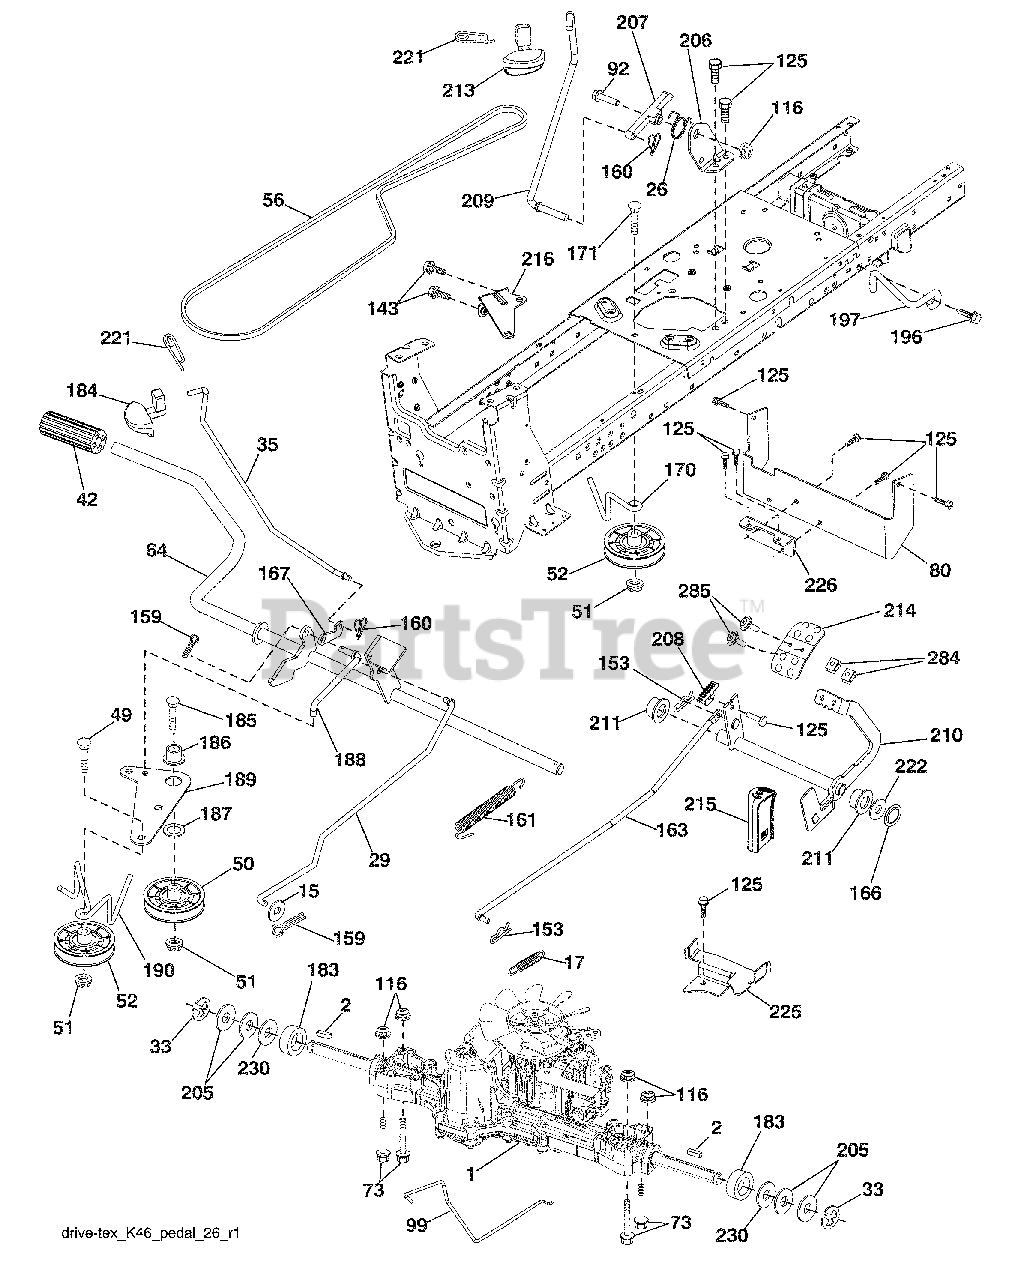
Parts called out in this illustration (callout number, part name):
1	Transaxle, TUFFTORQ K46 BT
15	Washer 13/32 x 13/16 x 16 Ga.
17	Spring, Brake
26	Spring Return Cruise
29	Rod, Brake
35	Rod, Brake, Park
42	Cover, Foot Pedal
50	Pulley Idler Flat
51	Lock Nut 3/8-16
52	Idler V-Groove 910" Offset
56	V-Belt, Drive
64	Shaft Asm. Pedal Brake Control
73	Bolt Hex Flghd 5/16-18 Gr. 5
80	Bracket Strap Torque
92	Bolt Fin Hex 5/16-18 unc x 1.25
99	Rod Spring Bypass
116	Nut Lock Hex Flange 5/16-18
125	Screw 5/16-18 x 3/4
143	Screw 5/16-18 x 1/2
153	Retainer Spring
159	Pin Cotter 1/8 x 3/4
160	Retainer Clip
161	Spring, Return, Clutch
163	Rod Pedal Control
166	Nut Push
167	Latch Brake Parking
170	Keeper Belt Centerspan
171	Bolt RDHD SQNK 3/8-16 unc x 2
183	Spacer Split
184	Handle Parking Brake
185	Bolt Rdhd Sqnk 3/8-16 x 2-3/4 Gr. 5
186	Spacer Retainer
187	Washer
188	Link Clutch Ground Drive
189	Bellcrank Ground Drive
190	Keeper Bellcrank Ground Drive
196	Screw 3/8-16 x 1
197	Bracket Clutch Anti-Rotation
206	Bracket Mount Latch Cruise
207	Latch Control Cruise
208	Gear Sector Control Cruise
209	Rod Control Cruise
210	Rocker Asm. Pedal Control
211	Bearing Nylon
213	Knob Control Cruise
214	Pedal Forward
215	Pedal Reverse
216	Bracket Pulley Idler
221	Retainer Spring Clip Handle
222	Washer 21/32 x 1-1/4 x 10 Ga.
225	Keeper Belt Trans.
226	Bracket Mount Touque
230	Washer Hardened
284	Nut U-CHNL 1/4-20 550DP .350 PNL
285	Screw PHD 1/4-20 Box Drive
